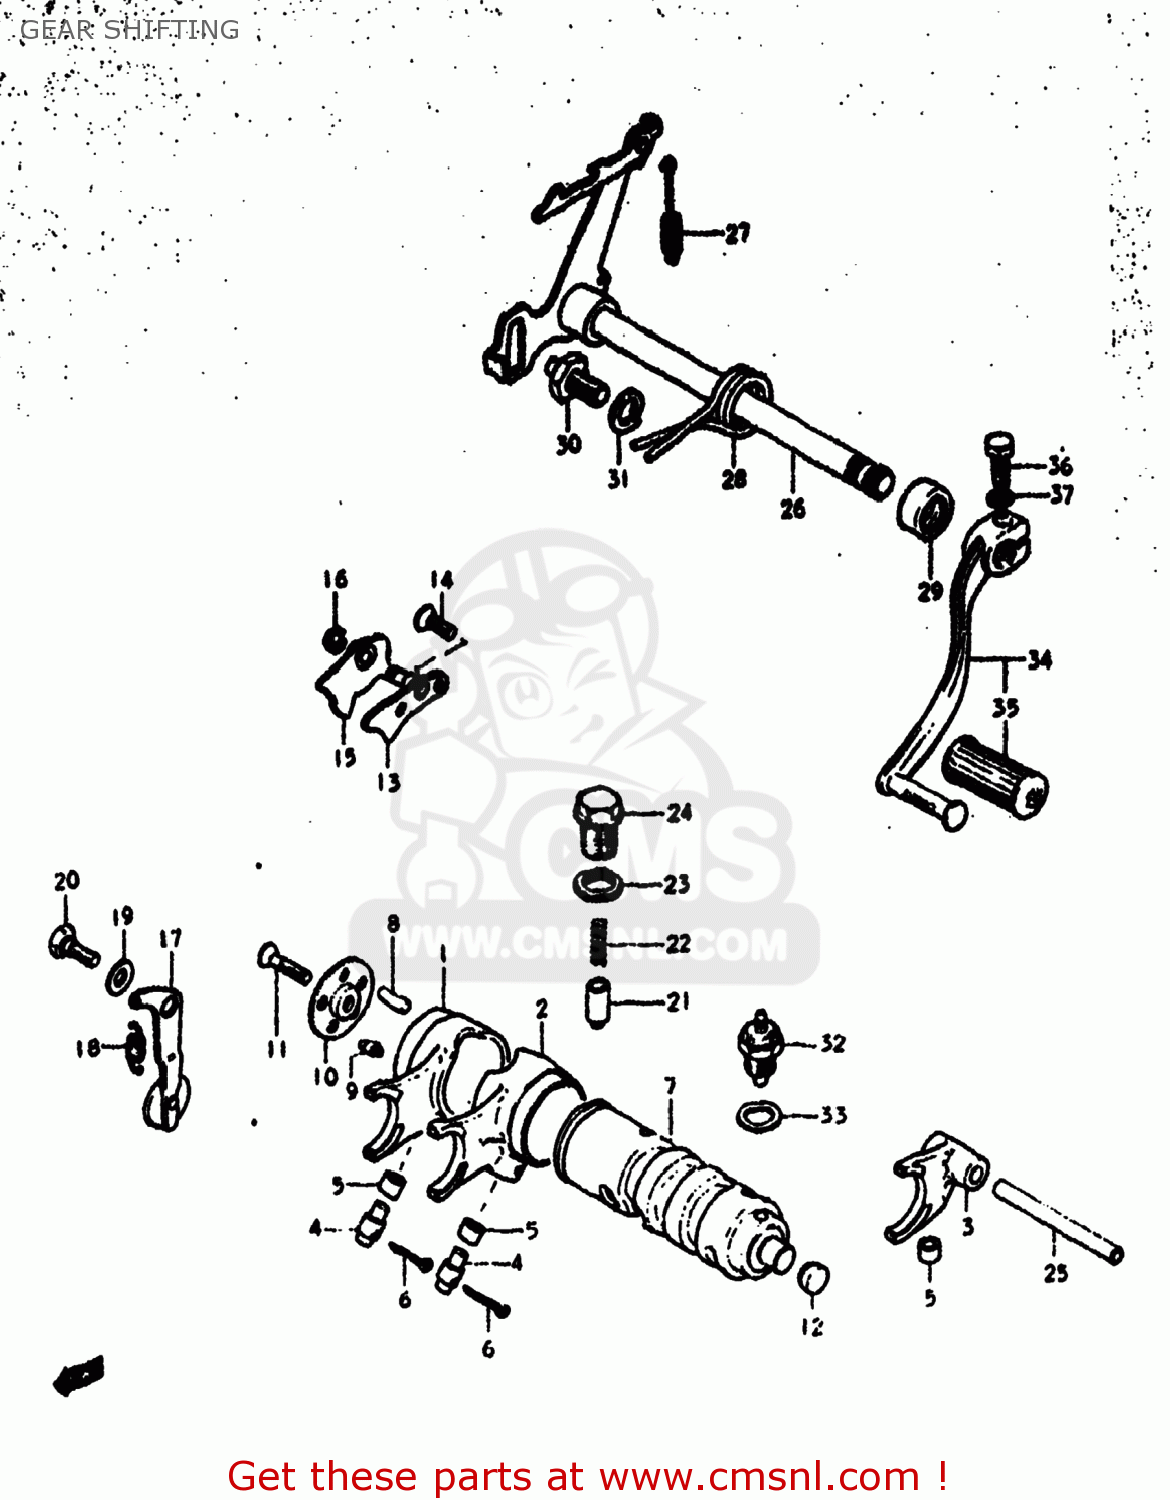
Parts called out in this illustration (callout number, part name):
1	FORK,GEAR SHIFT NO.1
2	FORK,GEAR SHIFT NO.2
3	FORK,GEAR SHIFT NO.3
4	PIN
5	SPACER
6	PIN 25X20
7	CAM,GEAR SHIFT
8	ROLLER(4X13.8)
9	PIN
10	RETAINER,GEAR SHIFT CAM DR PIN
11	SCREW
12	PLUG
13	GUIDE,GEAR SHIFT CAM
14	SCREW
15	PAWL,GEAR SHIFT CAM STOPPER
16	E RING
17	STOPPER,GEAR SHIFT CAM
18	SPRING
19	WASHER(6.5X16X2.3)
20	BOLT(6X16.1)
21	STOPPER,GEAR SHIFTING
22	SPRING
23	GASKET(14X19.2X2) (NAS)
24	BOLT,GEAR SHAFT CAM STOPPER
25	SHAFT,GEAR SHIFT FORK
26	SHAFT,GEAR SHIFT
27	SPRING
28	SPRING
29	OIL SEAL
30	STOPPER,GEAR SHIFT ARM
31	LOCK WASHER
32	SWITCH ASSEMBLY,NEUTRAL INDICATOR
33	GASKET(12.5X20X1) (NAS)
34	LEVER ASSEMBLY,GEAR SHIFTING
35	RUBBER,GEAR SHIFT PEDAL
36	BOLT
37	LOCK WASHER
